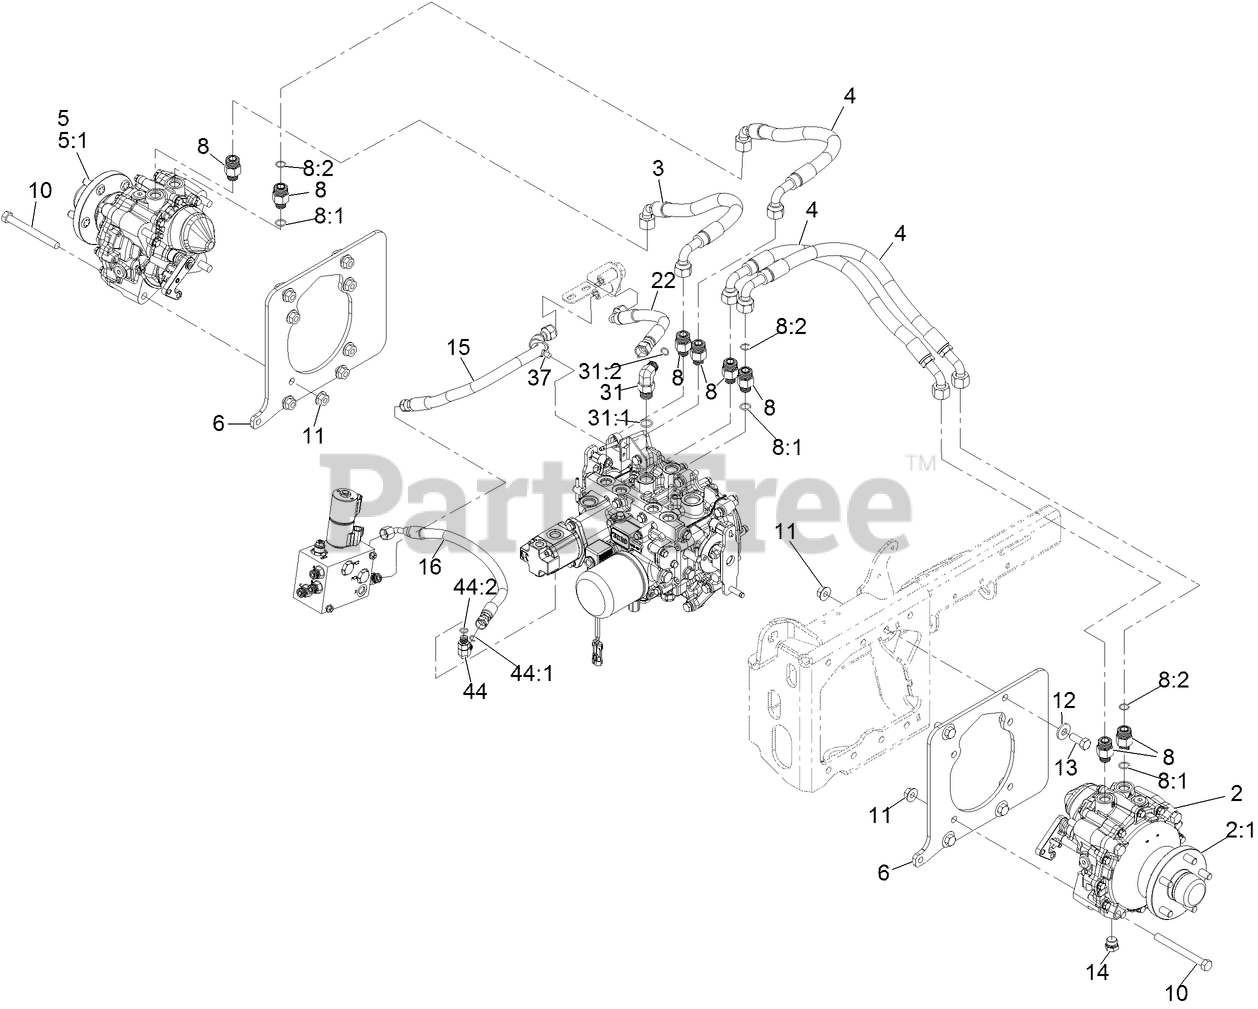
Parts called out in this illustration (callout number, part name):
2	MOTOR-HYD, LH
2:1	5 STUD WHEEL HUB KIT
3	HOSE ASM
4	HOSE ASM
5	MOTOR-HYD, RH
5:1	5 STUD WHEEL HUB KIT
6	PLATE-MOTOR
8	FITTING-STRAIGHT
8:1	O-RING
8:2	O-RING
10	SCREW-HH
11	NUT-HHF
12	WASHER-SPRING
13	SCREW-HH
14	PLUG-MAGNETIC
15	HOSE ASM
16	HOSE ASM
22	HOSE ASM
31	FITTING-ELBOW, 90 DEG
31:1	O-RING
31:2	O-RING
37	CLIP-TIE
44	FITTING-ELBOW, 90 DEG
44:1	O-RING
44:2	O-RING
